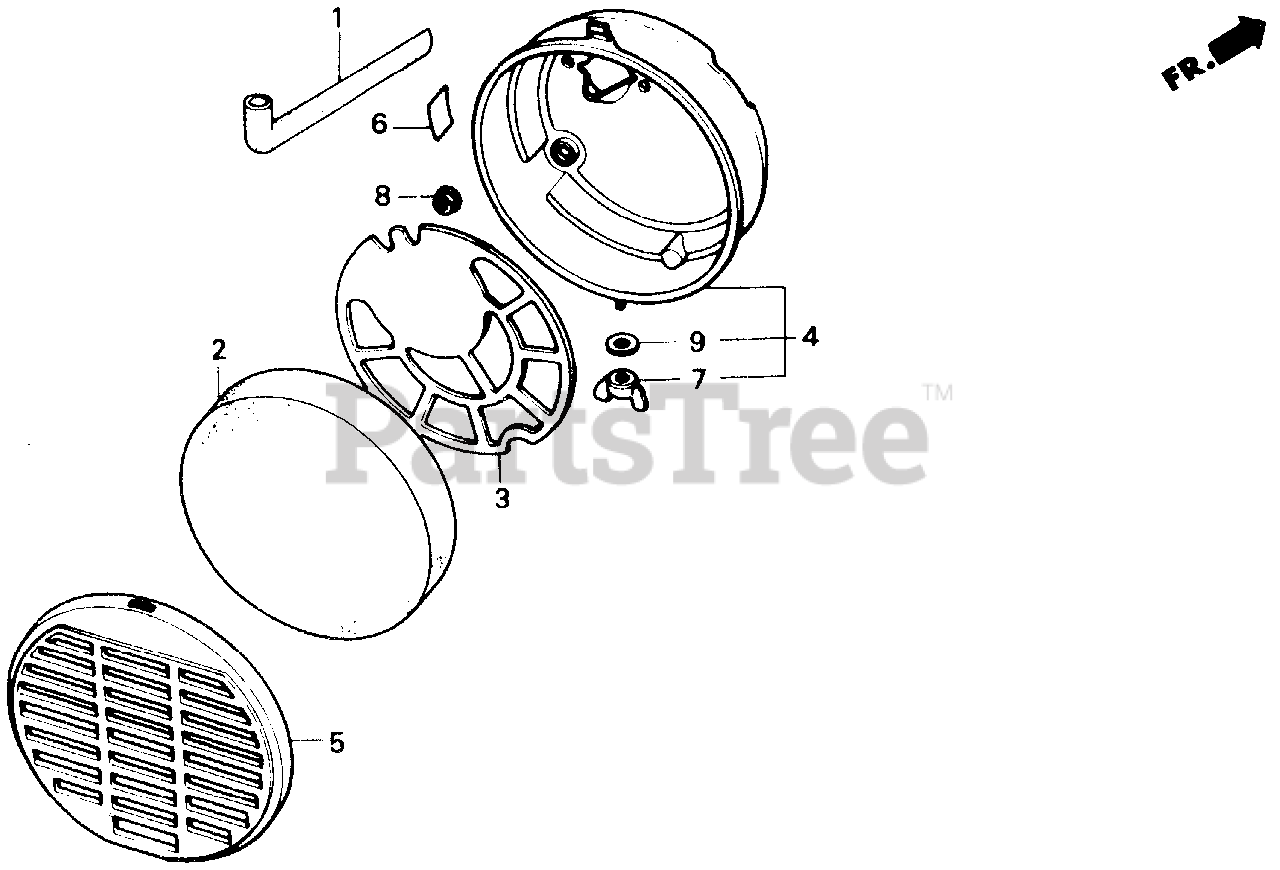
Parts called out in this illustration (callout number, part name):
1	TUBE, BREATHER
2	ELEMENT, AIR CLEANER
3	GRID, AIR CLEANER
4	HOUSING, AIR CLEANER
5	COVER, AIR CLEANER
6	MARK, CHOKE
7	NUT, TOOL BOX SETTING
8	NUT, FLANGE (6MM)
9	WASHER, PLAIN (6MM)
